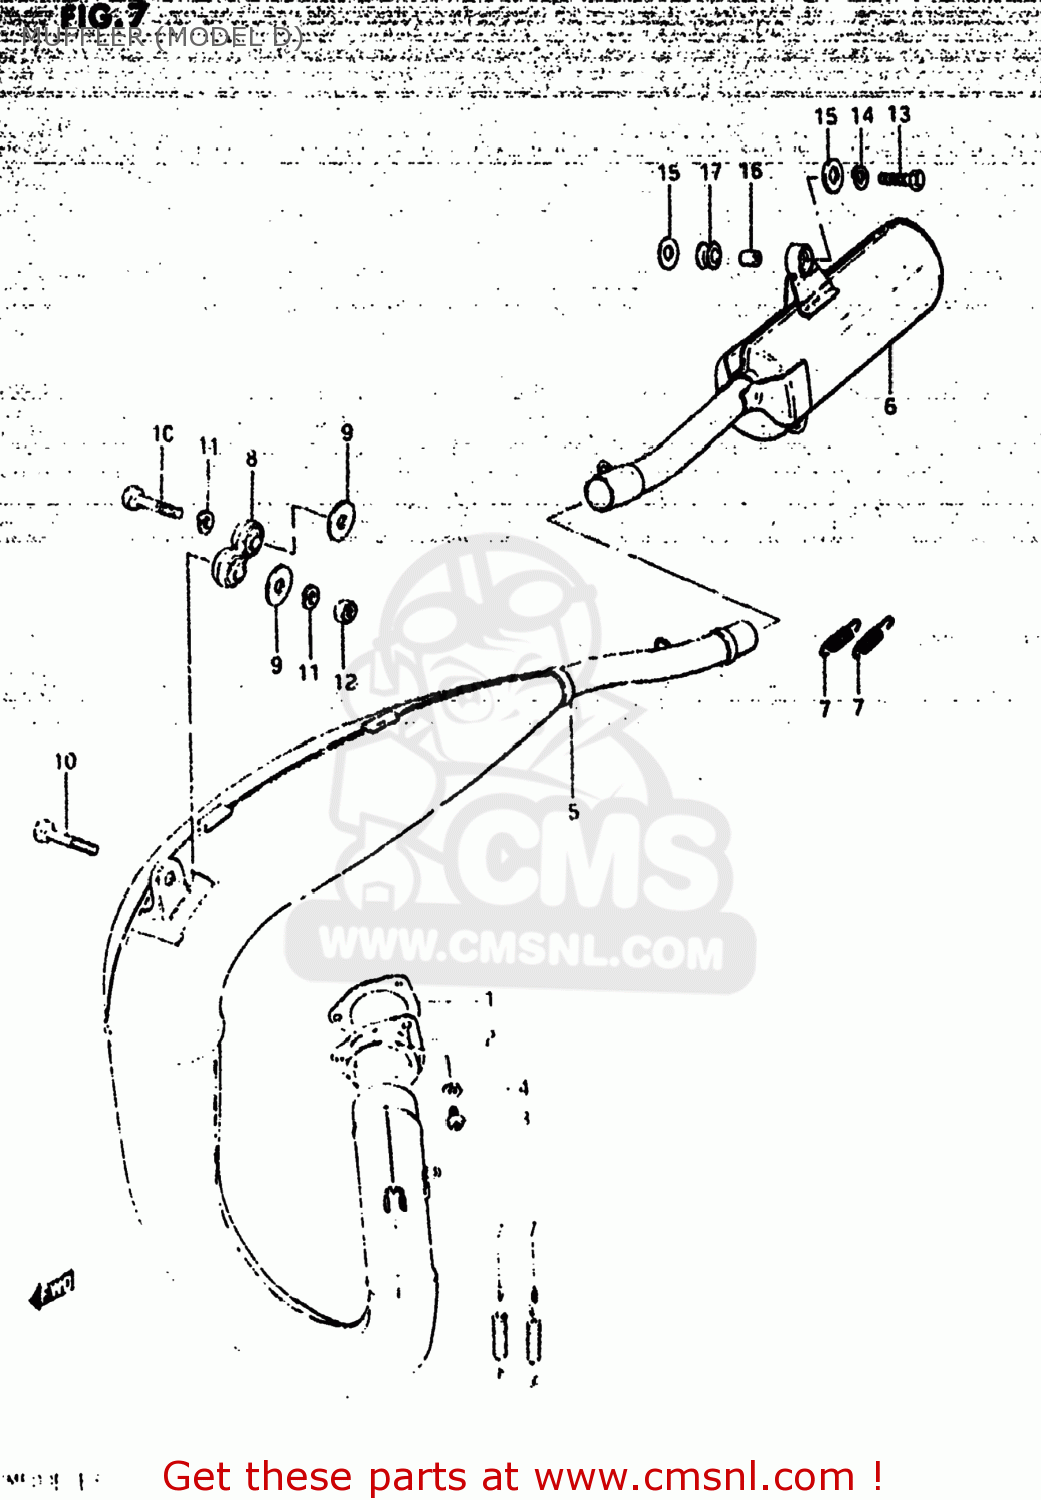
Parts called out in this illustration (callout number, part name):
1	GASKET,EXHAUST PIPE (MCA)
2	FLANGE,EXHAUST PIPE
3	SCREW
4	LOCK WASHER
5	BODY,MUFFLER
6	BODY,MUFFLER
7	SPRING
8	DAMPER,MUFFLER
9	WASHER
10	BOLT(8X32)
11	LOCK WASHER
12	NUT 8MM
13	BOLT(8X32)
14	LOCK WASHER
15	WASHER (8.5X29X1.6)
16	SPACER (8.6X12X17.5)
17	CUSHION
